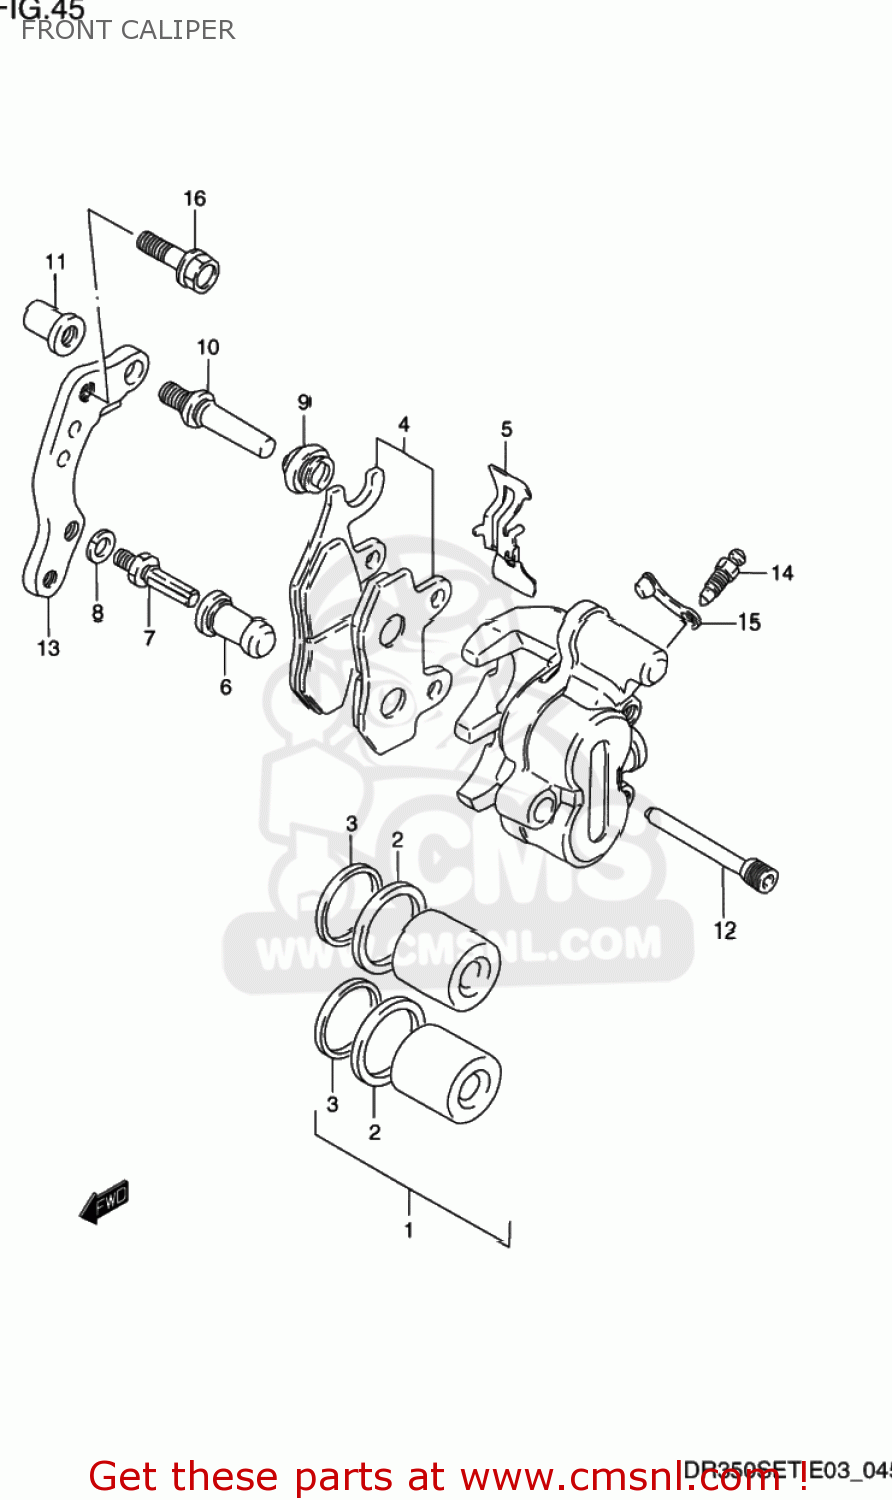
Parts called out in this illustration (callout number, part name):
1	PISTON SET
2	SEAL,PISTON
3	SEAL,DUST
4	PAD SET (NAS)
5	SPRING
6	BOOT
7	BOLT,PIN
8	WASHER,WAVE
9	BOOT
10	PIN,SLIDE
11	NUT
12	PIN,HOLDER
13	BRACKET
14	BLEEDER
15	CAP,BLEEDER
16	BOLT(8X24)
